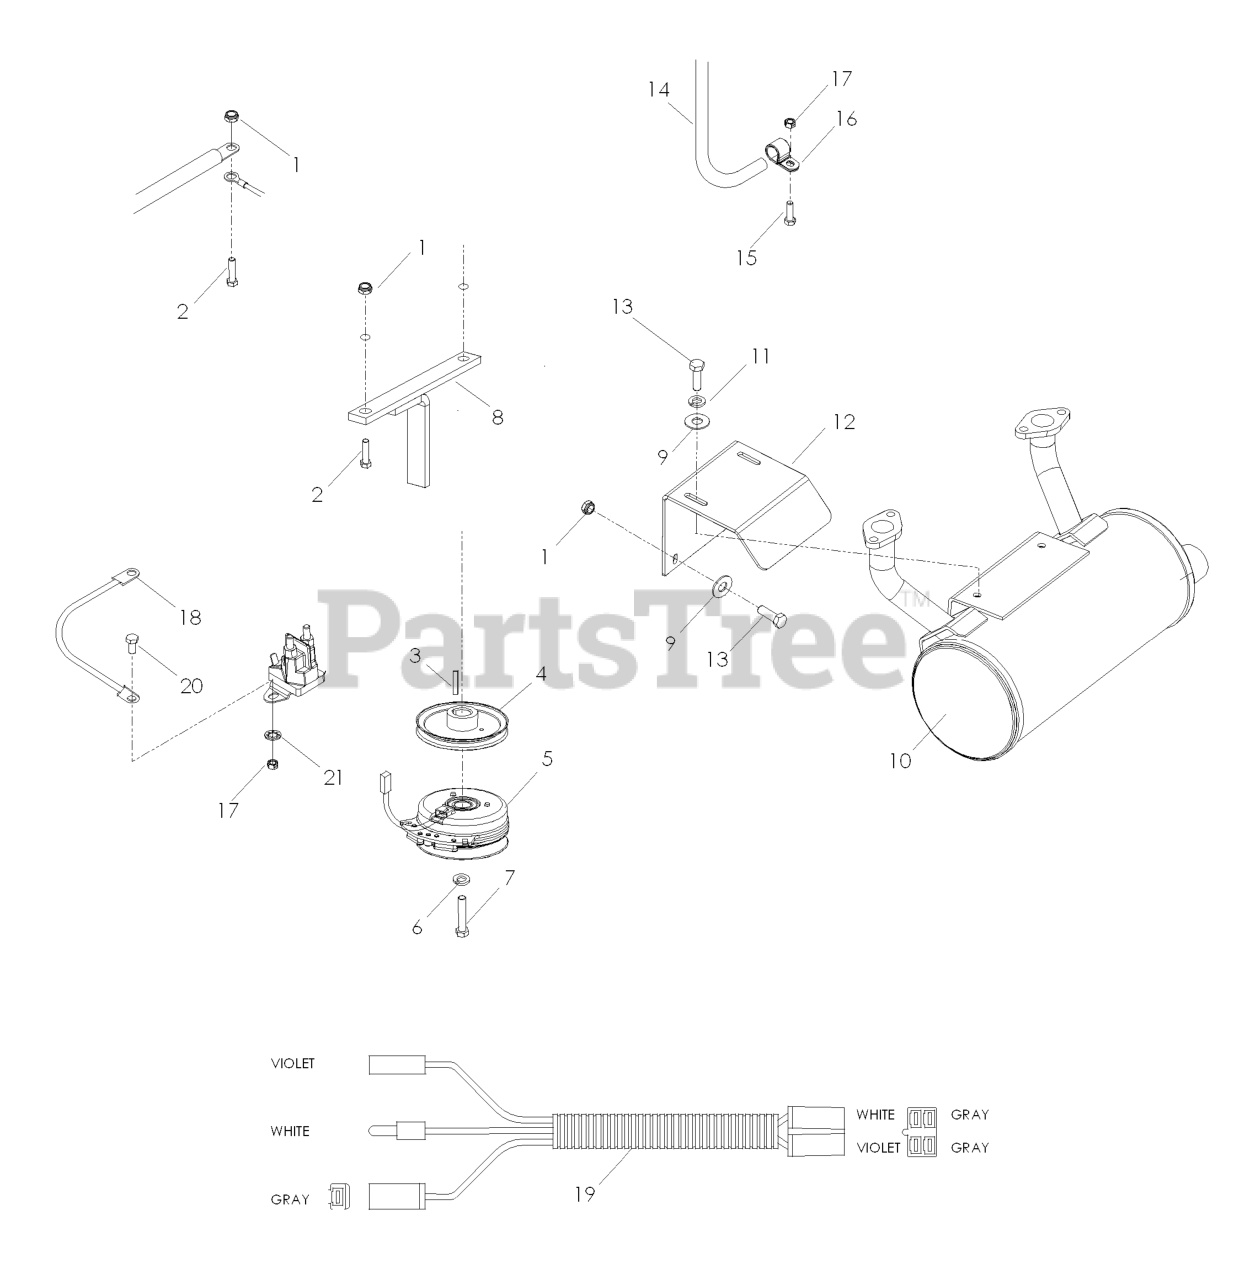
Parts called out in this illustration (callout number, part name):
1	NUT 5/16 NYLOC
2	HCS 5/16C X 1 3/4
3	KEY 1/4" SQ X 1 7/8"
5	ELECTRIC CLUTCH W/CABLE
6	WASHER 7/16 LOCK
7	BOLT 7/16F X 2 1/2
8	CLUTCH TIE DOWN
9	WASHER 5/16 FLAT
10	MUFFLER KAWASAKI GEN II
11	WASHER.LOCK.HVY.HLCL.SPR.5/16
12	MUFFLER BRACKET BLACK
13	HCS 5/16C X 1
14	OIL DRAIN HOSE
15	HCS 1/4C X 3/4 HCS
17	NUT 1/4C CENTER LOCK
18	GROUND WIRE (KAW)
19	KAW PIGTAIL
20	HCS 1/4C X 5/8
21	WASHER 1/4 INT TOOTH
